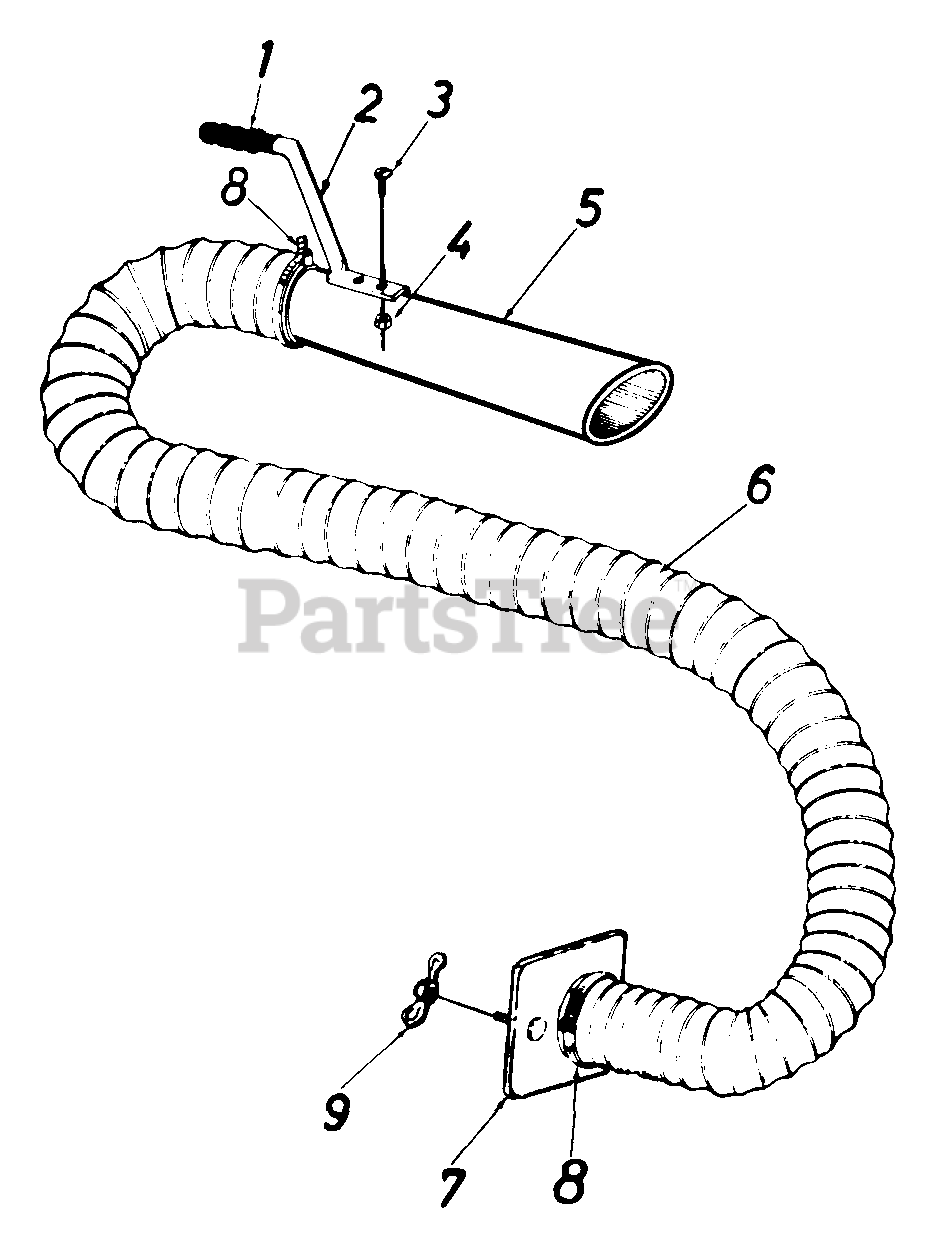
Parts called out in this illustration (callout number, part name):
1	Handle Grip
2	Handle
3	Truss Sems Scr. 10-24 x 1/2" Lg.
4	Hex Nut 10-24 Thd.
5	Hose Nozzle
6	Flexible Hose 4" Dia. x 10' Lg.
7	Hose Adapter Plate
8	Hose Clamp - For 4" Dia. Hose
9	Wing Nut 1/4-20 Thd.
